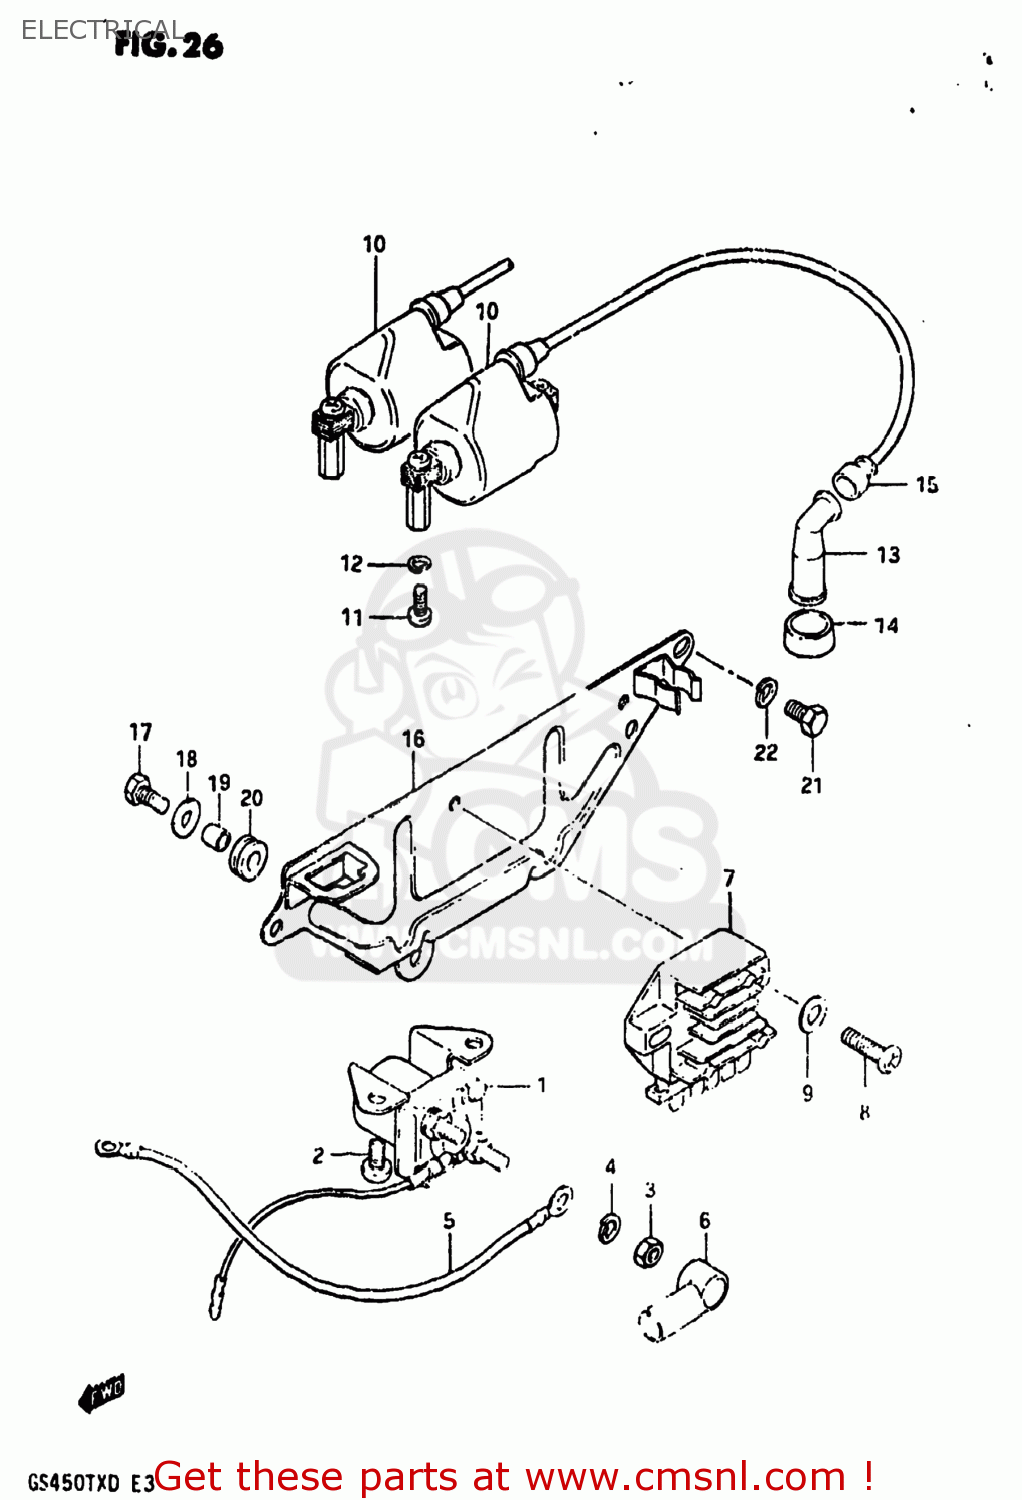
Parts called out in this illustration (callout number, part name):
1	RELAY ASSY,STARTING MOTOR
2	SCREW
3	NUT 6MM
4	LOCK WASHER
5	CORD,BATTERY MINUS
6	CAP,STARTER RELAY
7	RECTIFIER ASSEMBLY
8	SCREW
9	WASHER
10	COIL ASSEMBLY,IGNITION
11	SCREW
12	LOCK WASHER
13	CAP,SPARK PLUG
14	SEAL,SPARK PLUG
15	SEAL,SPARK PLU
16	HOLDER COMP,ELECTRONIC PARTS
17	BOLT
18	WASHER
19	SPACER (6.1X8X9.5)
20	CUSHION
21	BOLT
22	LOCK WASHER
